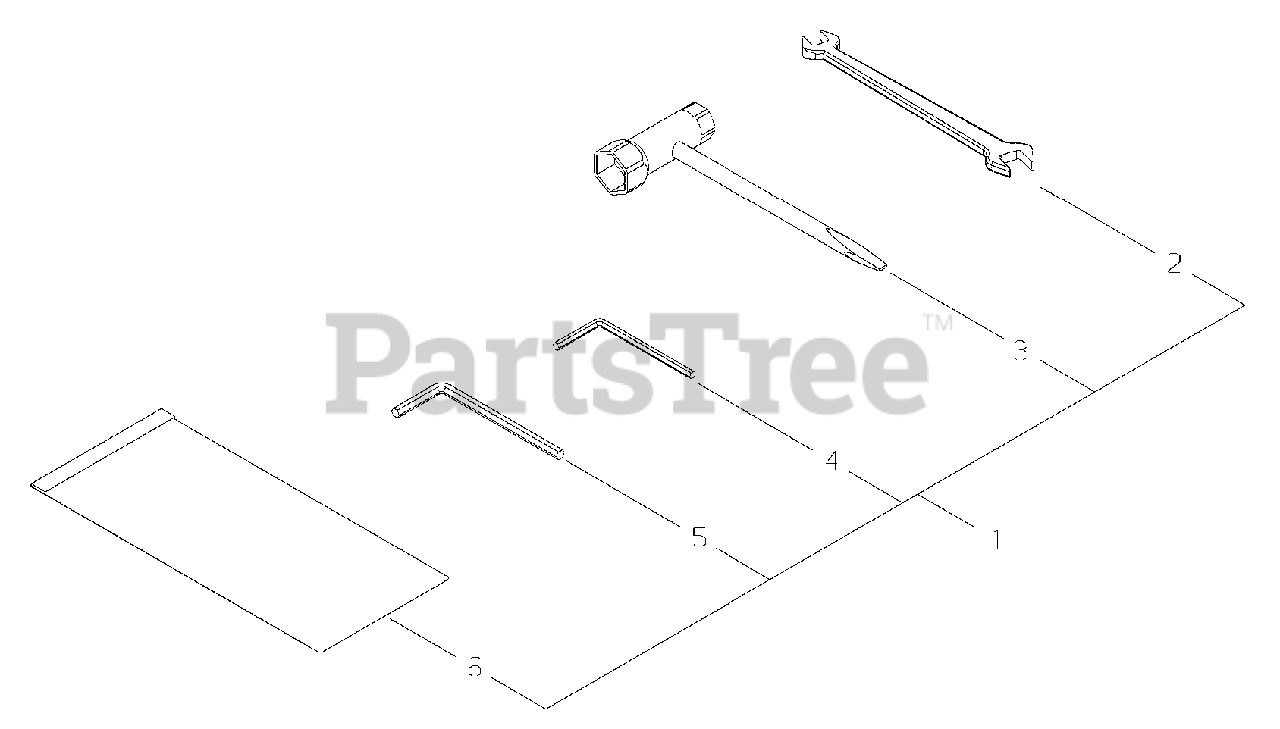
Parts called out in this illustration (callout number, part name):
1	TOOL KIT
2	SPANNER - 8X10mm
3	T-WRENCH - 13X16mm
4	HEX KEY - 4mm
5	HEX KEY - 6mm
6	BAG, TOOL
